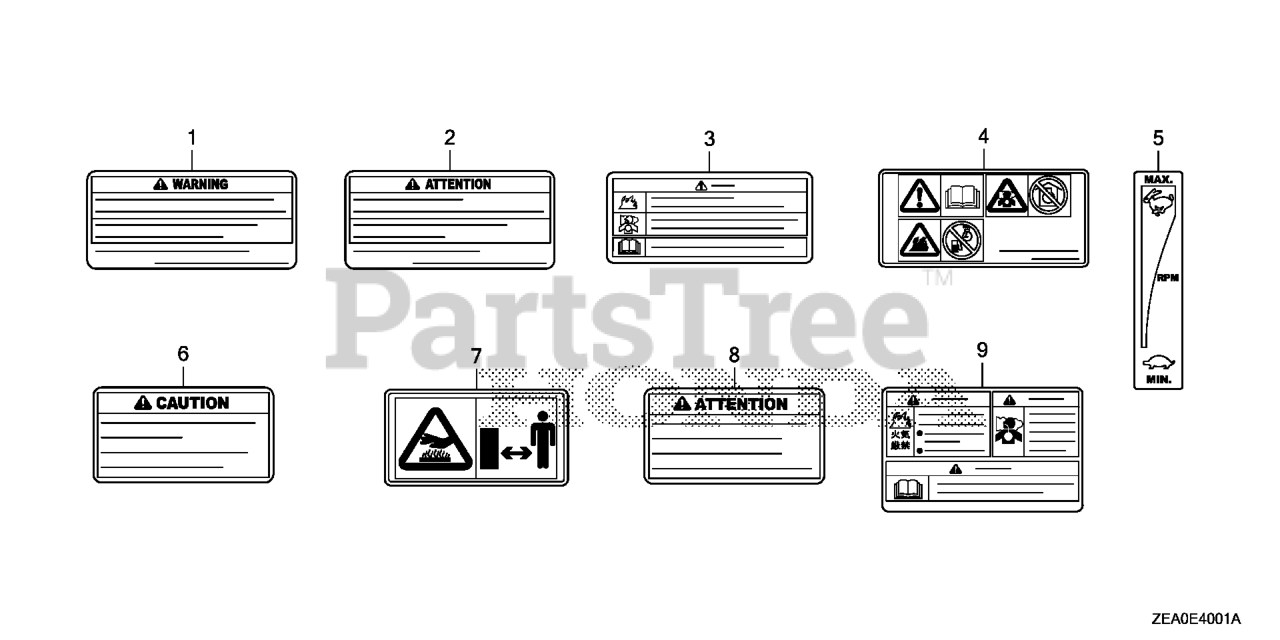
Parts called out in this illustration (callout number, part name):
1	MARK, OPERATOR CAUTION (ENGLISH)(MADE IN CHINA)
2	MARK, OPERATOR CAUTION (FRENCH)
6	MARK, EX. CAUTION (ENGLISH)
7	MARK, EX. CAUTION (PICTOGRAPH)
8	MARK, EX. CAUTION (FRENCH)
